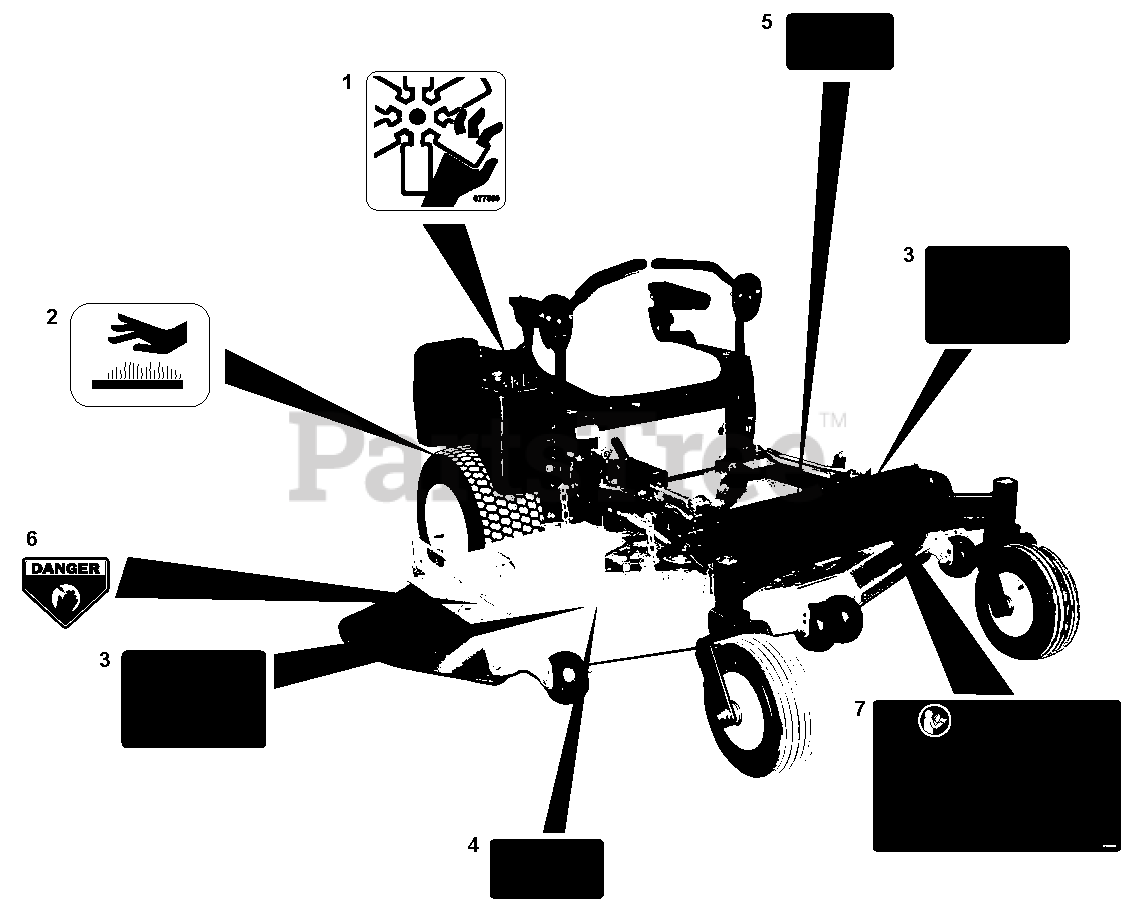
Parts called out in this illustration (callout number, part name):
1	Decal, Danger Fan
2	Decal, Hot Surface
3	Decal, Mower Safety
4	Decal, Safety Deck, Guarding
5	Decal, Safety Guarding
6	Decal, Danger
7	Decal, Safety, Main
